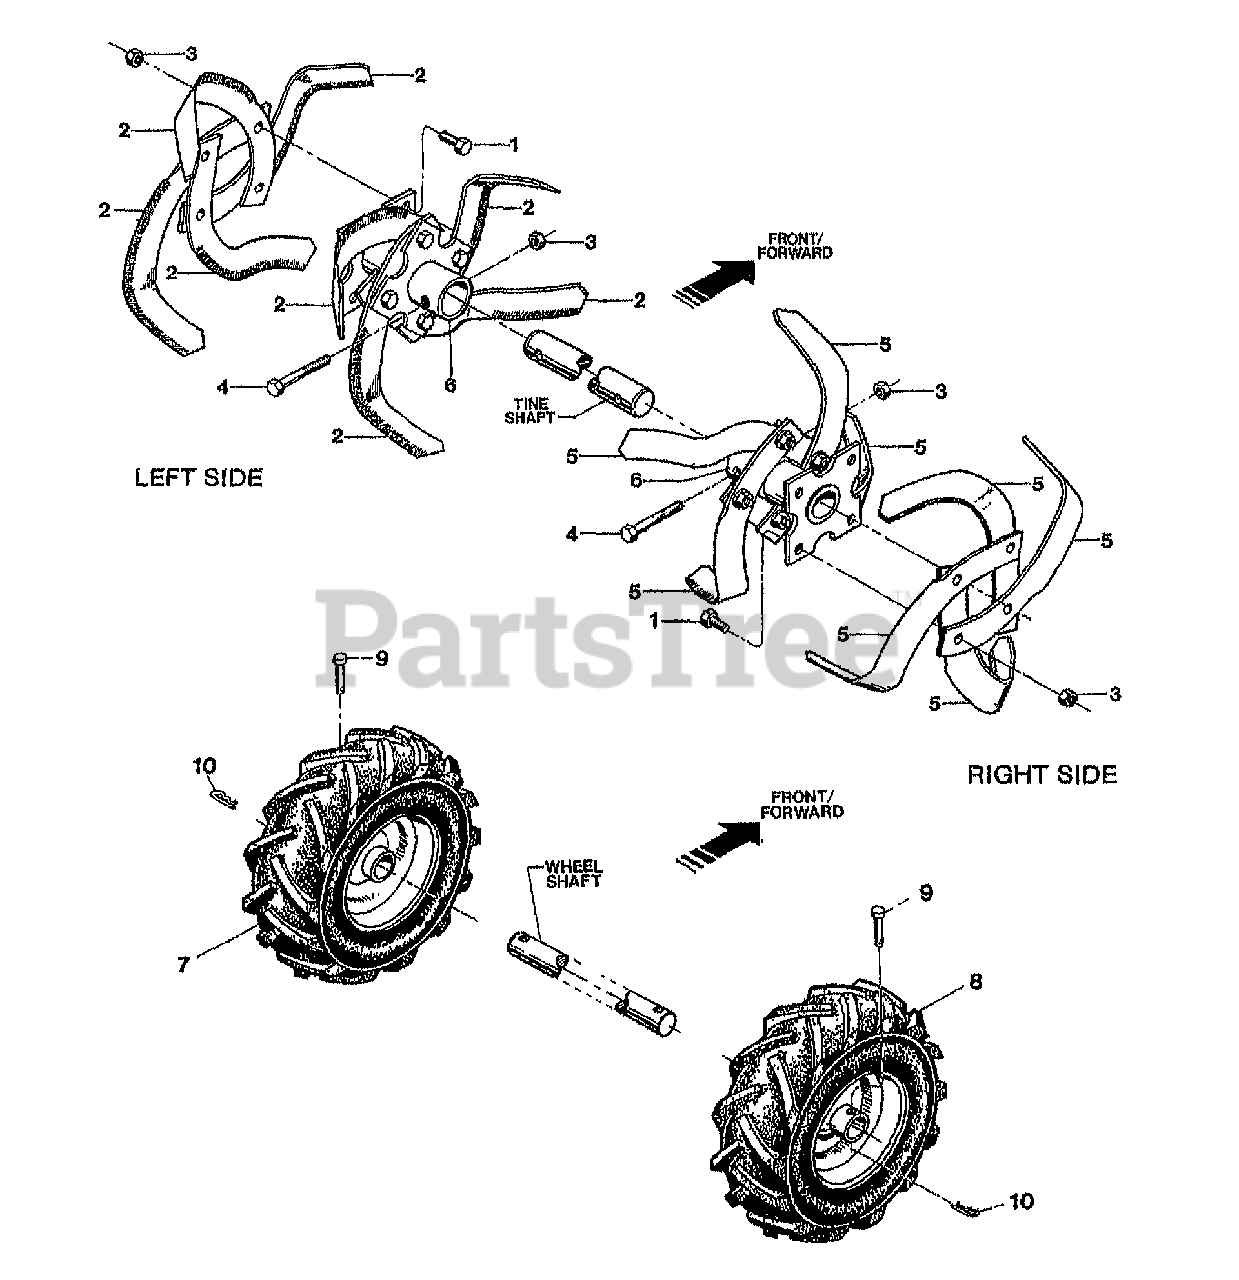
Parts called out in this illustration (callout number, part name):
1	SCR-HH 3/8-16X1.0 G5 ZP
2	TINE-BOLO RIGHT
3	NUT-LOCK 3/8-16
4	SCR-HH 3/8-16X2.00 G8 (TINE HOLDER TO TILLER SHAFT)
5	TINE-BOLO LEFT
6	HOLDER-TINE JUNIOR
6	HOLDER-TINE T/B TUFFY {12155}
7	ASSM-TIRE&WHL LH GRAY
8	ASSM-TIRE&WHL RH GRAY
9	PIN-CLEVIS
10	PIN-CLIP .08
